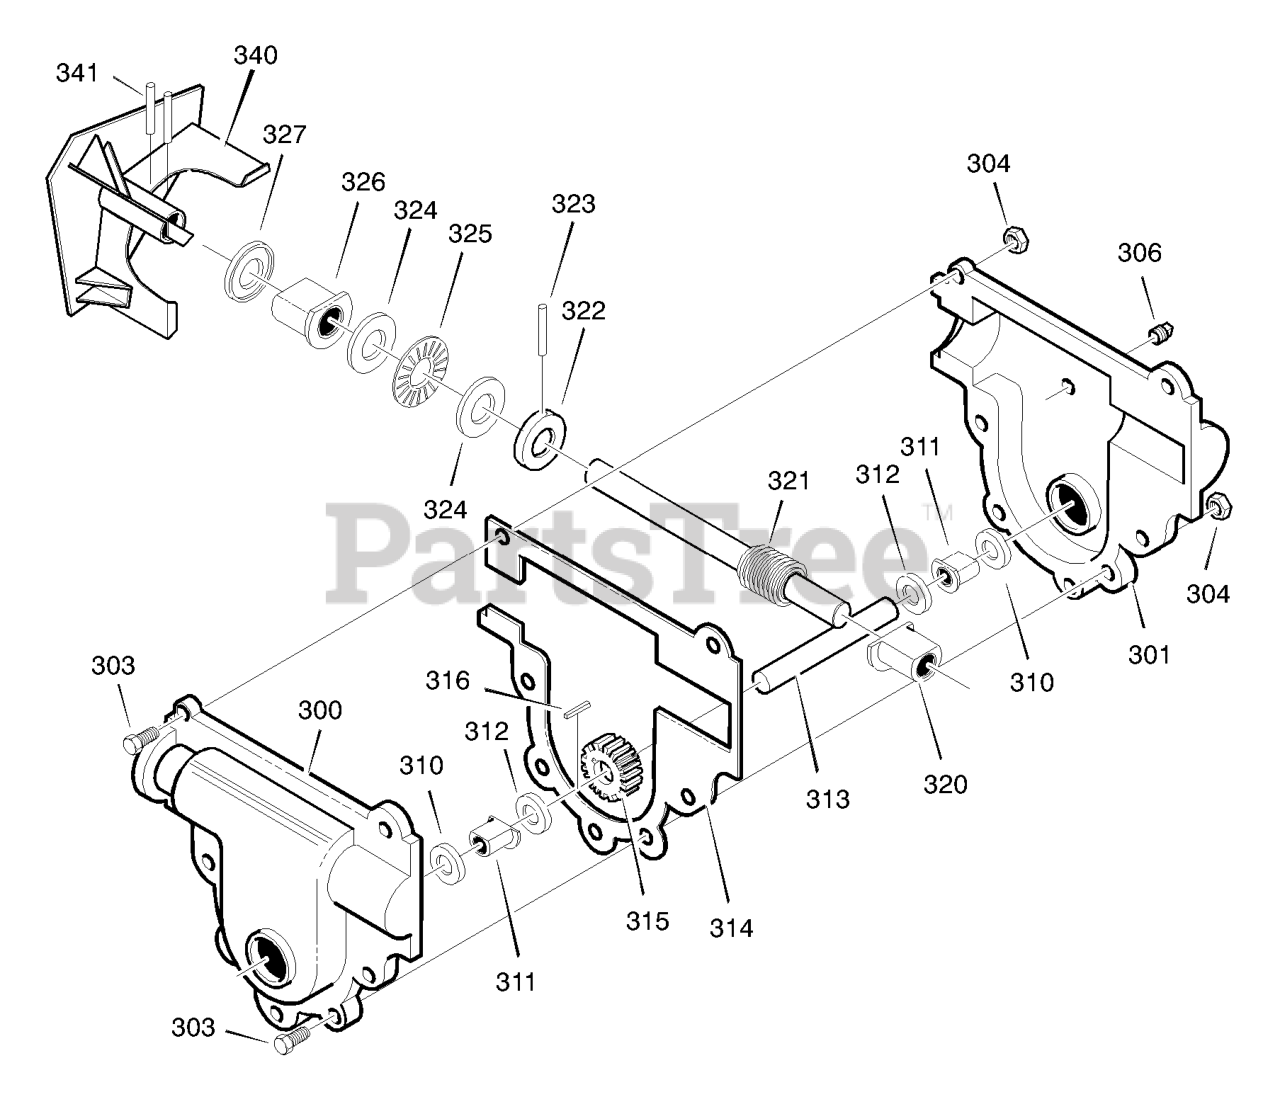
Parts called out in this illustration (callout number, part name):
300	CASE, GEAR, RH
301	CASE, GEAR, LH
306	SCREW
310	SEAL, OIL
311	BEARING, FL
312	WASHER, FLAT
313	SHAFT, OUTPUT
315	GEAR, WORM
316	KEY, WOODRUFF
320	BRNG, FL
321	SHAFT, INPUT
322	COLLAR, THRUST
323	PIN, SPRING
324	WASHER, FLAT
325	BRNG, ROLL
326	BRNG, FL
327	SEAL, OIL
340	IMPELLER ASSEMBLY
341	PIN, SPRING
